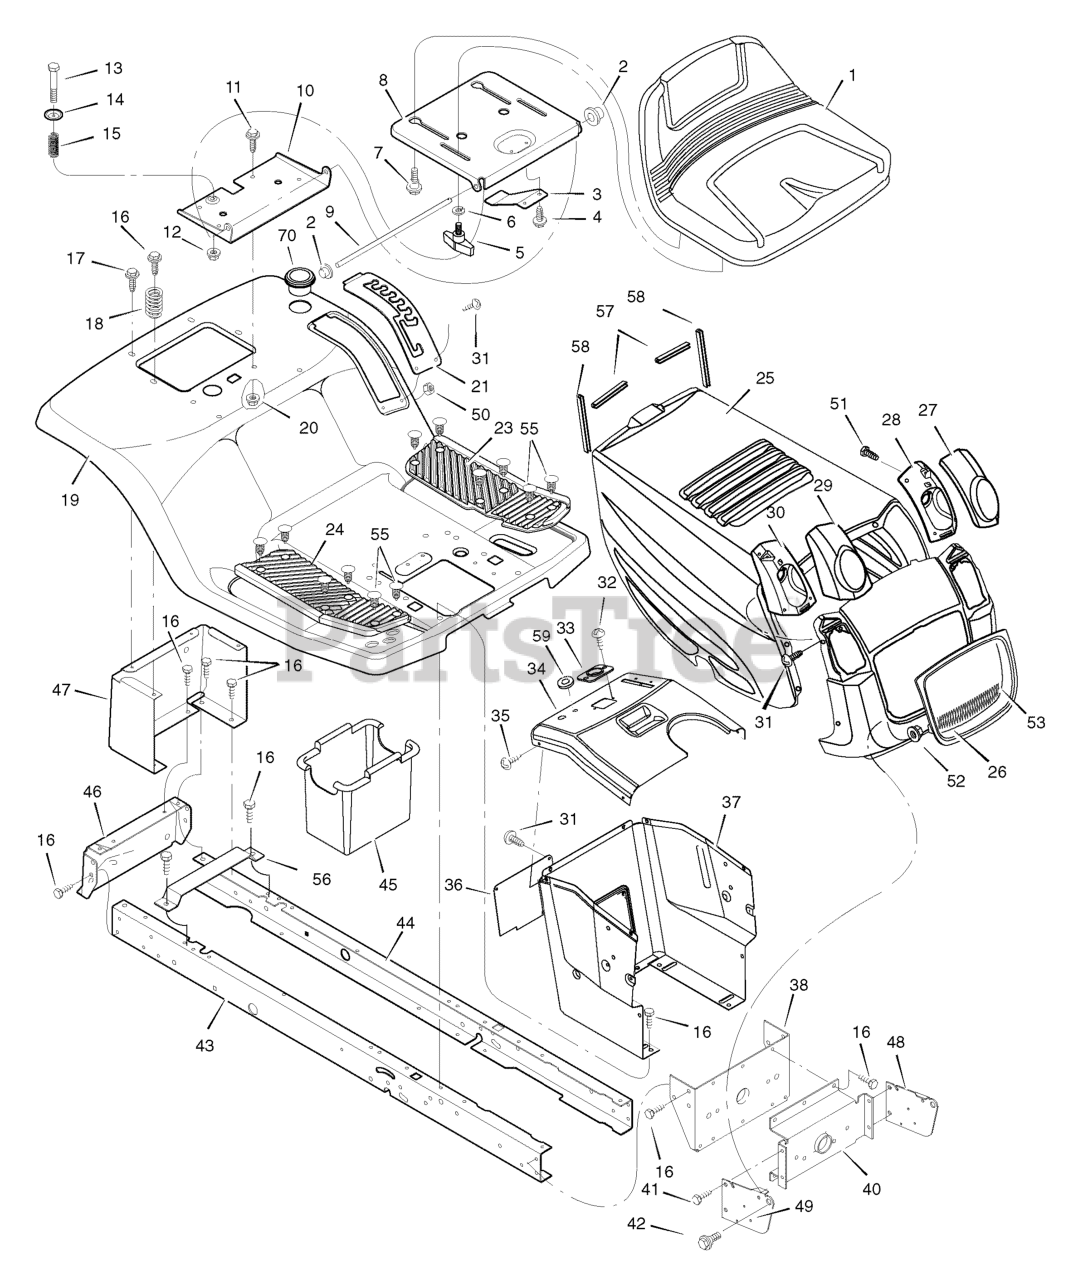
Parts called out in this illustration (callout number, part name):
1	SEAT
2	CAP, Push 0n
5	BOLT, Wing
6	WASHER
7	BOLT, Shoulder
8	SUPPORT, Seat
9	ROD, Pivot
10	BRACKET, Pivot
11	BOLT
13	BOLT, Shoulder
20	NUT
21	PLATE, Index
23	MAT, Left
24	MAT, Right
25	HOOD
26	GRILLE
27	LENS, Left
28	HOUSING, Left Headlamp
29	LENS, Right
30	HOUSING, Right Headlamp
33	BEARING, Steering
34	DASH
36	PANEL, Access
37	SUPPORT, Dash
38	BRACKET, Rear Hanger
40	AXLE, Hanger
41	BOLT, Hex
42	BOLT, Shoulder
43	FRAME, Right
44	FRAME, Left
45	CONTAINER, Battery
46	PLATE, Hitch
47	PANEL, Rear
48	Support, Left Grille
49	Support, Right Grille
53	INSERT, Grille
55	FASTENER, Panel
56	SUPPORT, Battery
57	TRIM, Hood (3.75")
58	TRIM, Hood (6.5")
59	GROMMET, Parking Brake
70	HOLDER, Cup
